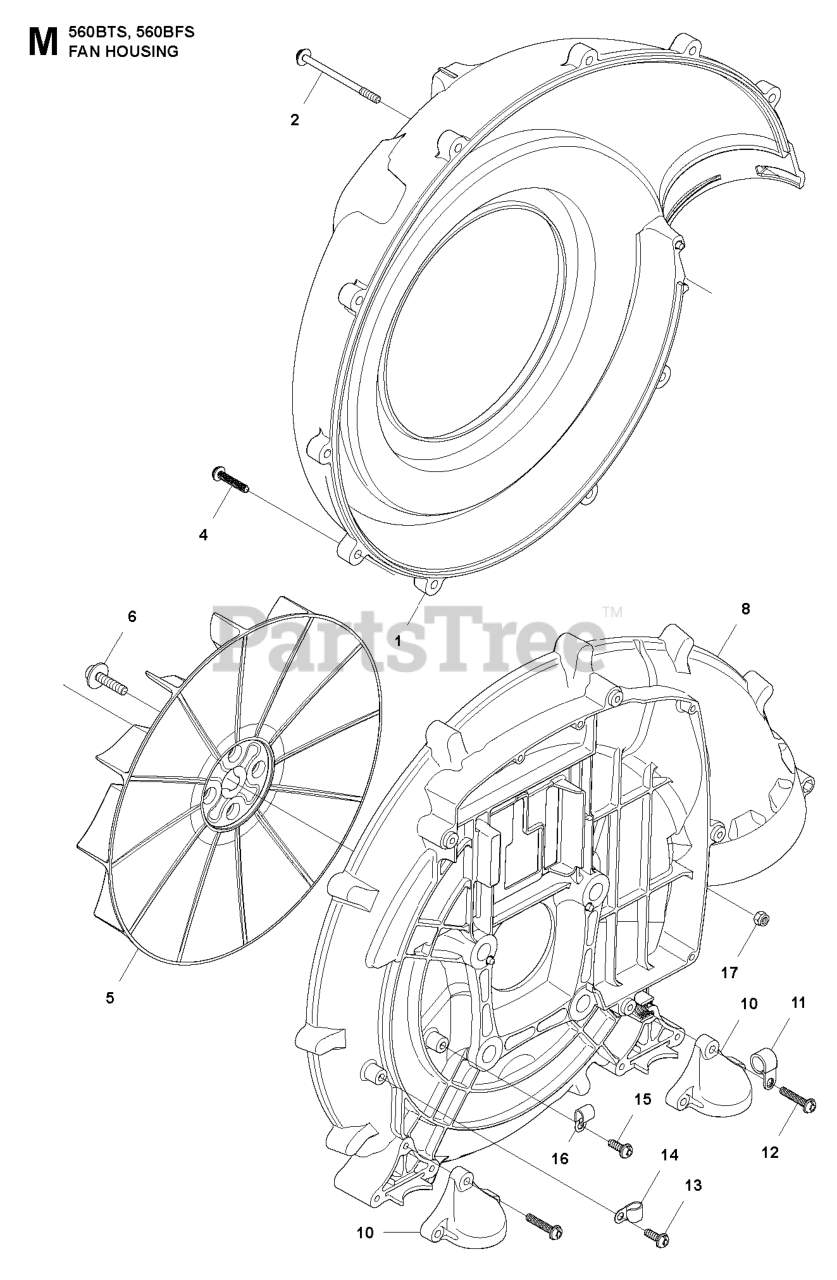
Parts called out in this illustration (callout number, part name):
10	BRACKET DAMPNER
14	CLAMP
16	CLAMP
